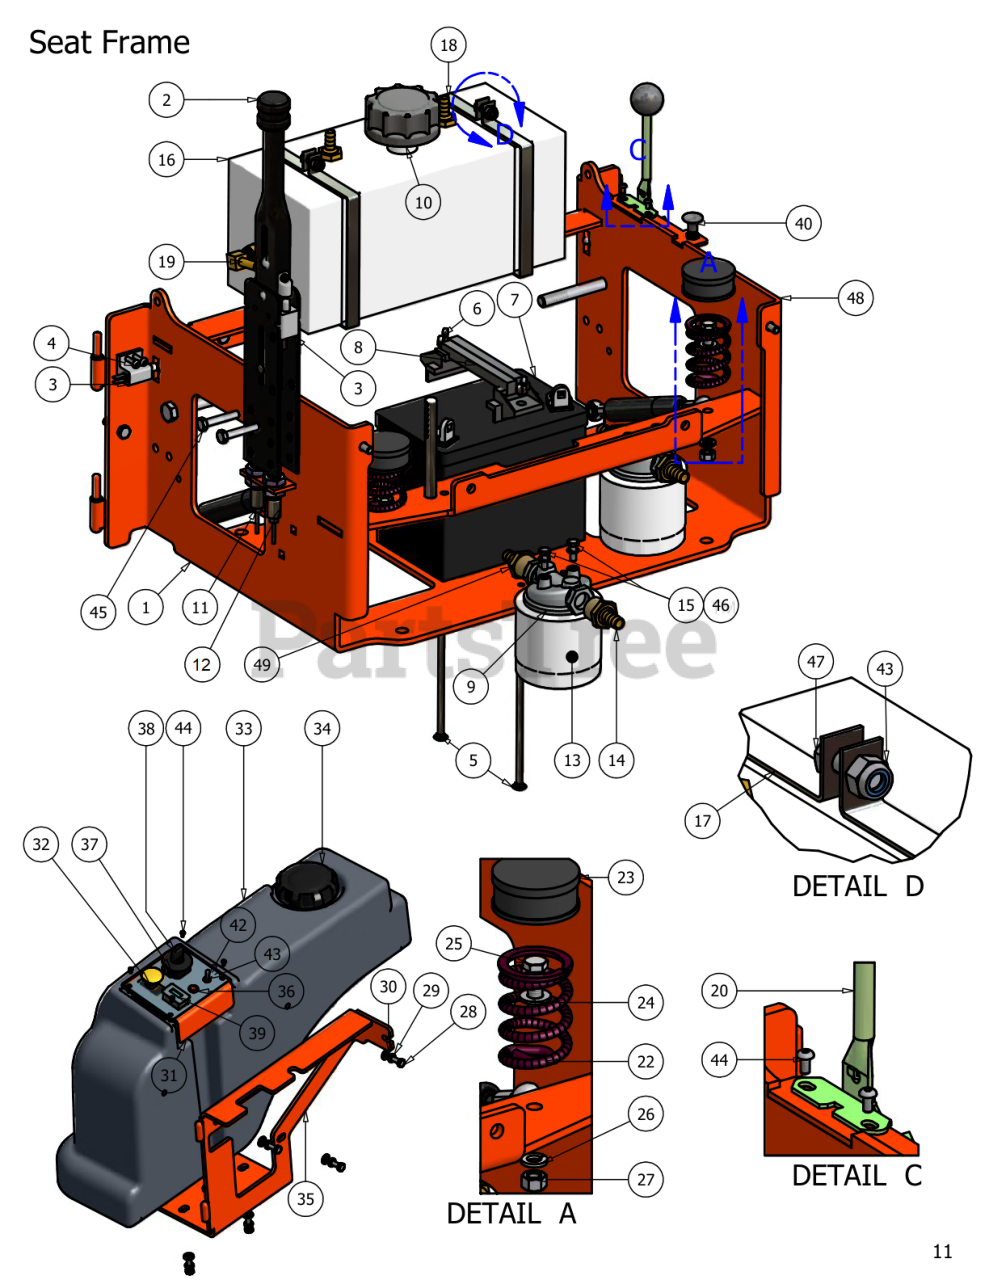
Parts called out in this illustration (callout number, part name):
1	Seat Frame
2	Brake Lever
3	Brake Handle Switch
4	1024 x 1" Bolt
5	7" Stove Bolt
6	1/4" Wing Nut
8	Battery hold-down
9	Filter Head
10	Hydraulic Tank Cap
11	Short Brake Cable
12	Long Brake Cable
13	Hydraulic Filter
14	Filter Head Fitting
15	1/4" x 3/4" Hex Bolt
16	Hydraulic Tank
17	Hydraulic Tank Strap
18	3/8" X 3/8" Hose Barb
19	1/2" x 1/2" Filter Head Fitting (90 Degree)
20	Throttle (23 Briggs, 26 Kawasaki, 30 Kohler)
21	Throttle (32 Briggs)
22	Seat Spring
23	1 1/2" Spring Cap Cover
24	3/8" Flat Washer
25	3/8" x 1 1/2" Hex Bolt
26	3/8" Lock Washer
27	3/8" Hex Nut
28	5/16" x 1" Hex Bolt
29	5/16" Lock Washer
30	5/16" Flat Washer
31	Control Panel
32	Blade Engager
33	Right Fuel Tank
33	Left Fuel Tank
35	Right Tank Swing Arm
35	Left Tank Swing Arm
37	Ignition Switch
38	Ignition Key
39	Tachometer
41	Choke (All Kohler Engines)
43	5/16" Nylock Nut
44	1024 X 5/8" Buttonhead Bolt
45	5/16" x 1 3/4" Hex Bolt
46	1/4" Lock Washer
47	5/16" x 3/4" Hex Bolt
48	Piezo Buzzer
49	1/2" x 3/8" Barb Fitting
